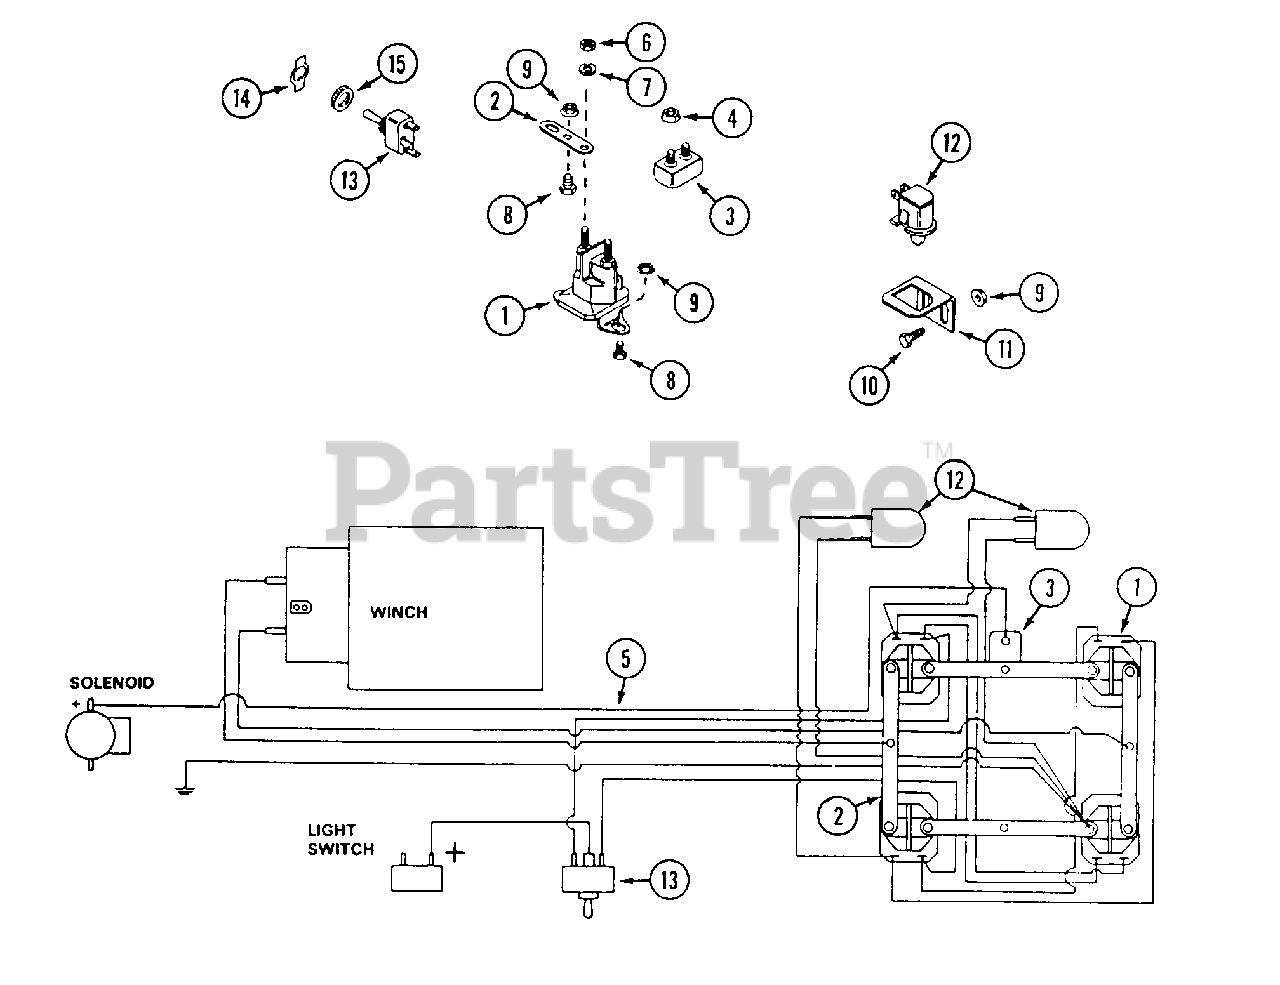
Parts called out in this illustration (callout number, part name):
1	SOLENOID - 12V
2	STRAP
3	BREAKER - 40 amp, 12V
4	NUT - #10 - 32
5	HARNESS - wire
6	NUT - 1/4" - 20
7	LOCKWASHER - 1/4"
8	BOLT - 1/4" - 20 x 1/2"
9	NUT - 1/4" - 20 flange
10	BOLT - 1/4" - 20 x 3/4"
11	BRACKET - switch
12	SWITCH - limit
13	SWITCH - lift
14	DECAL - switch identification
15	NUT - 15/32" - 32, switch
